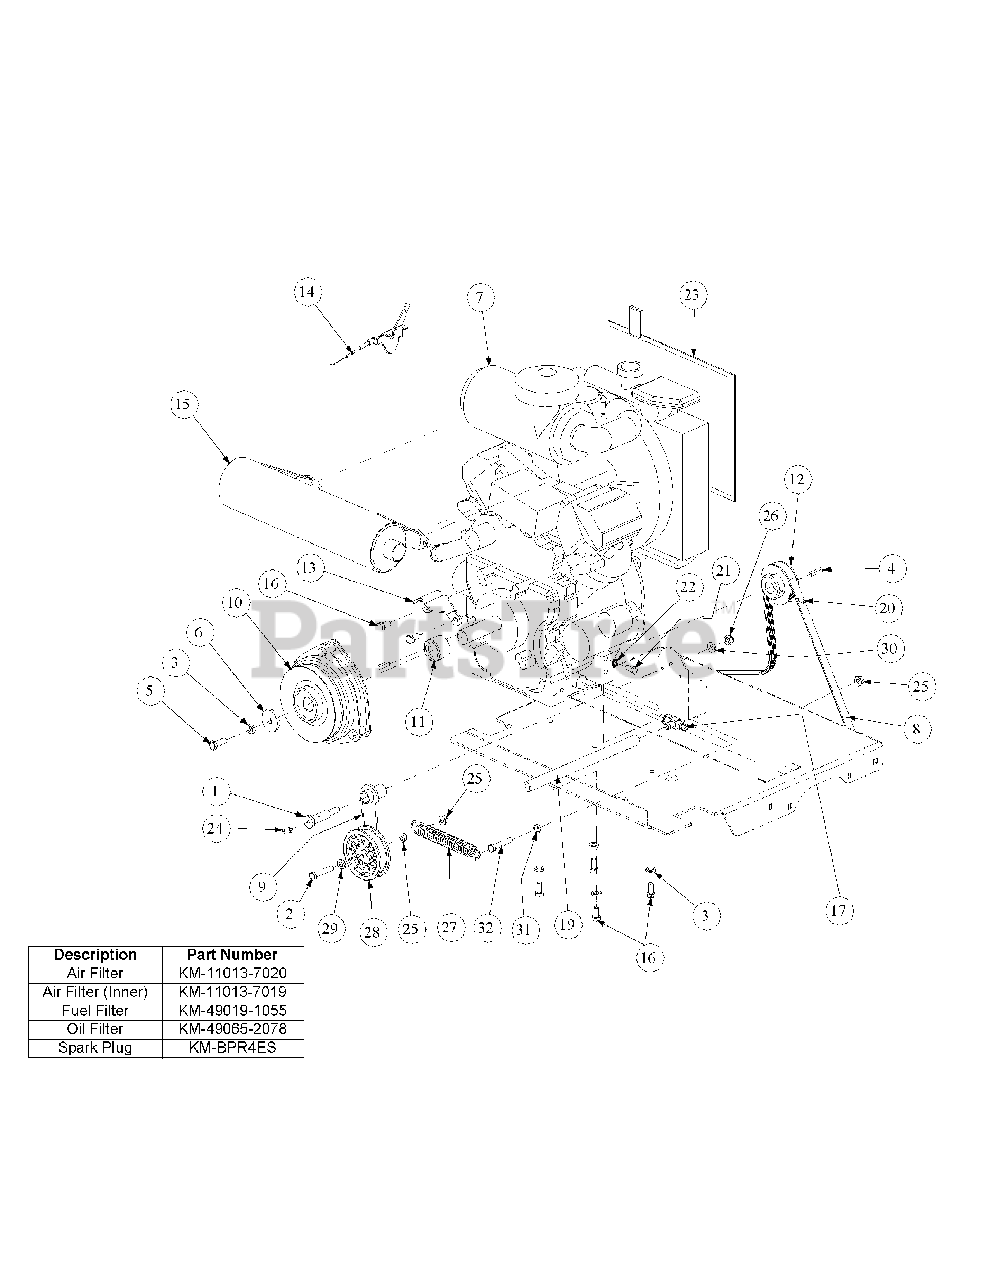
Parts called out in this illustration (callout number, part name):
1	Shoulder Screw, 7/16-14
2	Hex Cap Screw, 3/8-16 x 2.25
3	Lock Washer, 7/16
4	Key Stock, 1/4 x 1/4 x 1-1/4
5	Hex Head Cap Screw, M10 x 1.5, 30mm
6	Flat Washer, 7/16 ID x 1.75 OD x .25
7	29HP Digital Fuel Injection Engine, Kawasaki
8	V Belt
9	Idler Arm Assembly
10	Clutch Brake
11	Spacer, 1.75 OD x 1.135 ID x 1.125
12	Pulley, 3.05 OD x 1.0 Bore
13	Clutch Retainer Bracket
14	Throttle, Control Cable, 47.0
15	Muffler, 29HP Horizontal, Kawasaki
16	Hex Head Cap Screw, M10 x 1.5, 20mm
17	Oil Valve
18	Shaft, Kawasaki Output
19	Oil Drain Extension Hose
20	Set Screw, 5/16-18
21	Hex Head Cap Screw, M10 x 1.25, 20mm
22	Washer, 3/8 ID, External Tooth
23	Screen, Kawasaki 29HP Radiator
24	Grease Fitting, 1/4-28 90 Degree
25	Nut, 3/8-16, Hex Flange Lock
26	Nut, 7/16-14, Nylock
27	Extension Spring, 1.0 OD x 5.00
28	Idler Pulley, 3.5 OD
29	Washer, 3/8
30	Washer, .469 ID x .875 OD x .105
31	Jam Nut, 3/8-16
32	Hex Cap Screw, 3/8-16 x 1.25
